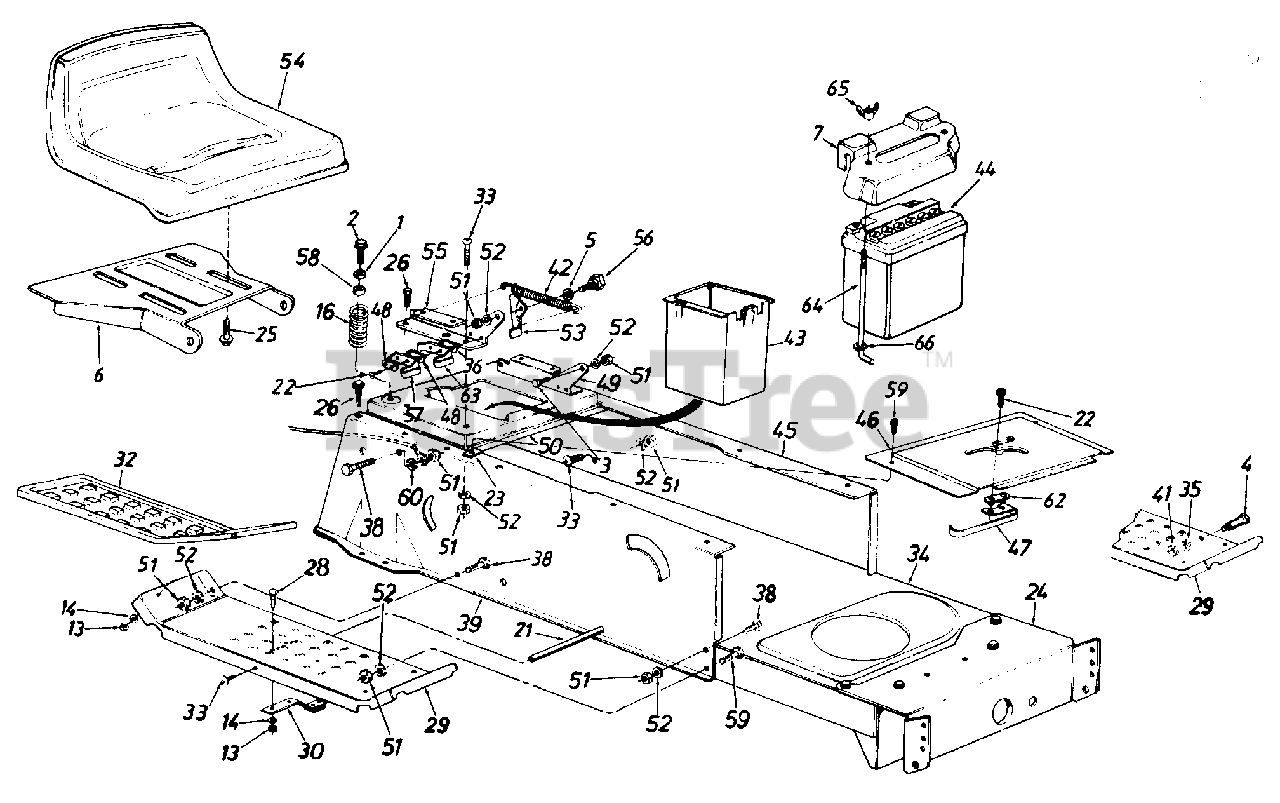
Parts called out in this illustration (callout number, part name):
1	Fl-Wash. .344" I.D. x .875"
2	Hex Wash. Hd. Tap Scr. 5/16-18 x 1.25" Lg.
3	Shld. Bolt .437" Dia. x .162"
4	Shld. Bolt .50" Dia. x .84"
5	Spr-Wash. .445" I.D. x .75
6	Seat Pivot Bracket
7	Battery Cover
13	Hex Nut 1/4-20 Thd.
14	L-Wash. 1/4" I.D.
16	Compression Spring
21	Running Board Rod
22	Hex Wash. Hd. AB-Tap Scr. #8 x .50" Lg.
23	Speed Nut #10Z
24	Front Pivot Brkt.
25	Hex Tap Scr. 3/8-16 x .75"
26	Hex Wash. Hd. AB-Tap Scr. 5/16 x .75" Lg.
28	Carriage Bolt 1/4-20 x .62"
29	Running Board
30	Blade Brake Ass'y.
32	Rubber Foot Pad-L.H.
33	Truss Mach. Scr. 5/16-18 x .75" Lg.
34	Lower Frame
35	L-Wash. 3/8" I.D.
36	Insulator Boss Plate
38	Hex Bolt 5/16-18 x .75" Lg.
39	Upper Frame-R.H.
41	Hex Nut 3/8-16 Thd.
42	Extension Spring 5.31" Lg.
43	Utility Box
44	Battery
45	Upper Frame-L.H.
46	Shift Cover
47	Reverse Safety Switch
48	Insulator Plate
51	Hex Nut 5/16-18 Thd.
52	L-Wash. 5/16" I.D.
53	Seat Lift Brkt.
54	Seat 10-5/8" High
57	Spring Switch
58	Bushing
59	Truss Hd. Scr. 5/16-18 x 1.0" Lg.
60	External L-Wash. 5/16" I.D.
62	Insulator Nut Plate
63	Safety Switch
64	Battery Hold Down Rod
65	Wing Nut Plastic 1/4-20 Thd.
66	Push Nut
